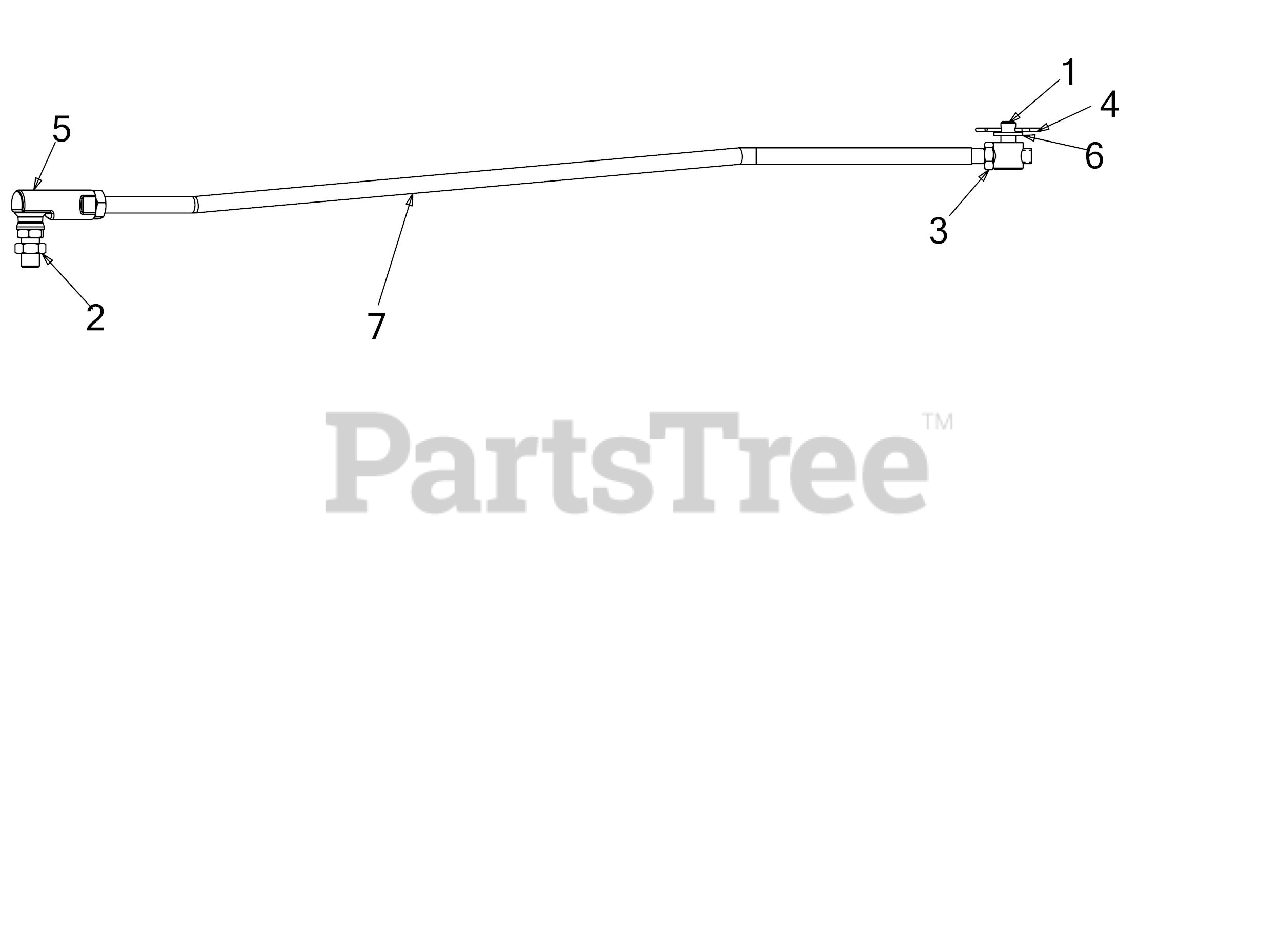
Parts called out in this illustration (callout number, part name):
1	FERRULE 5/16-18 x .312
2	HEX JAM NUT 3/8X24
4	BOW TIE COTTER PIN 1/4-5/16
5	BALL JOINT
6	FLAT WASHER ID-.320 x .598
